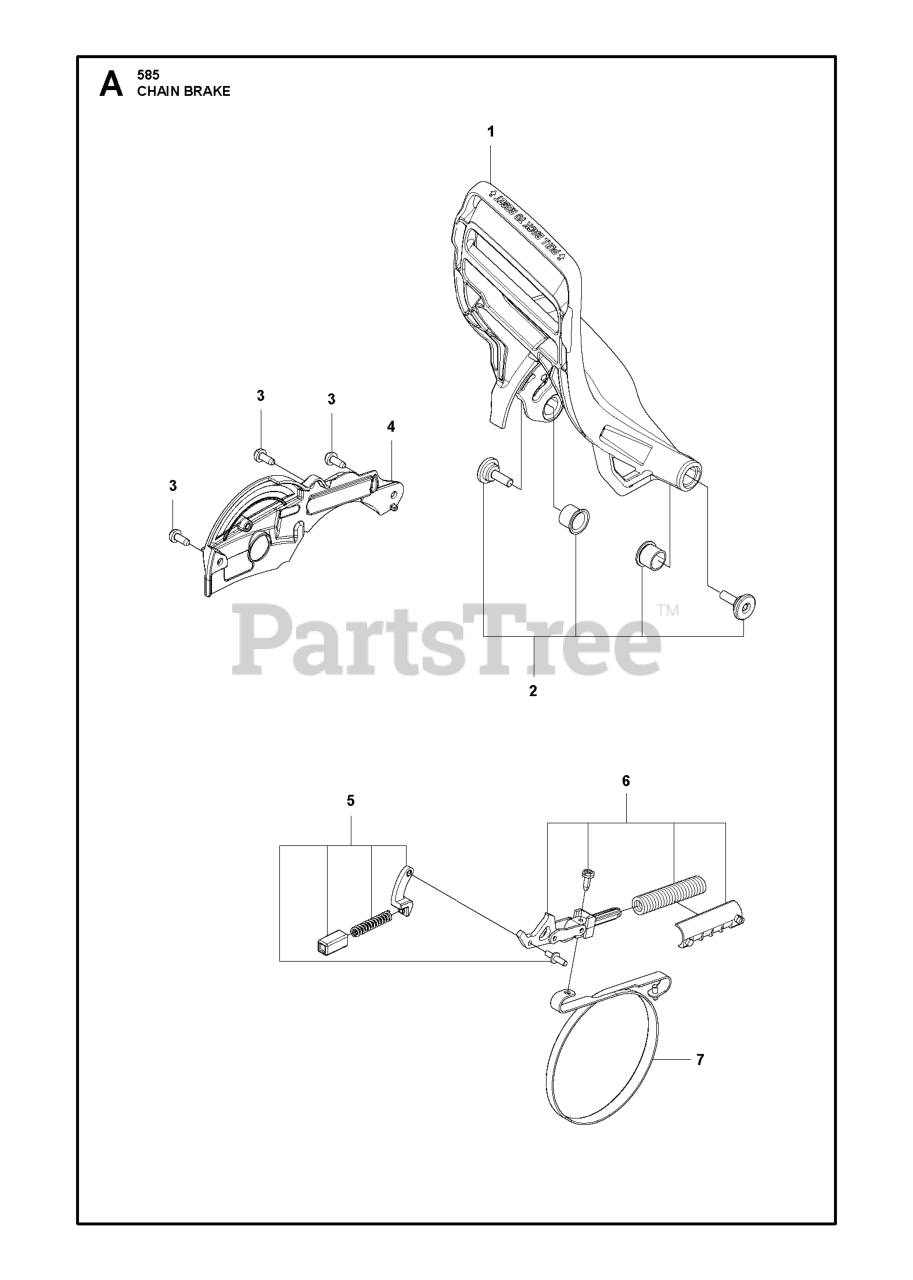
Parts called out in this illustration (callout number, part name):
1	HAND GUARD
2	SCREW KIT HANDGUARD 90CC
3	SCREW HEXALOBULAR PAN HEAD M4
4	COVER BRAKE
5	CATCH KIT 90CC
6	KNEE JOINT ASSY KIT 90 CC
7	BRAKE BAND
